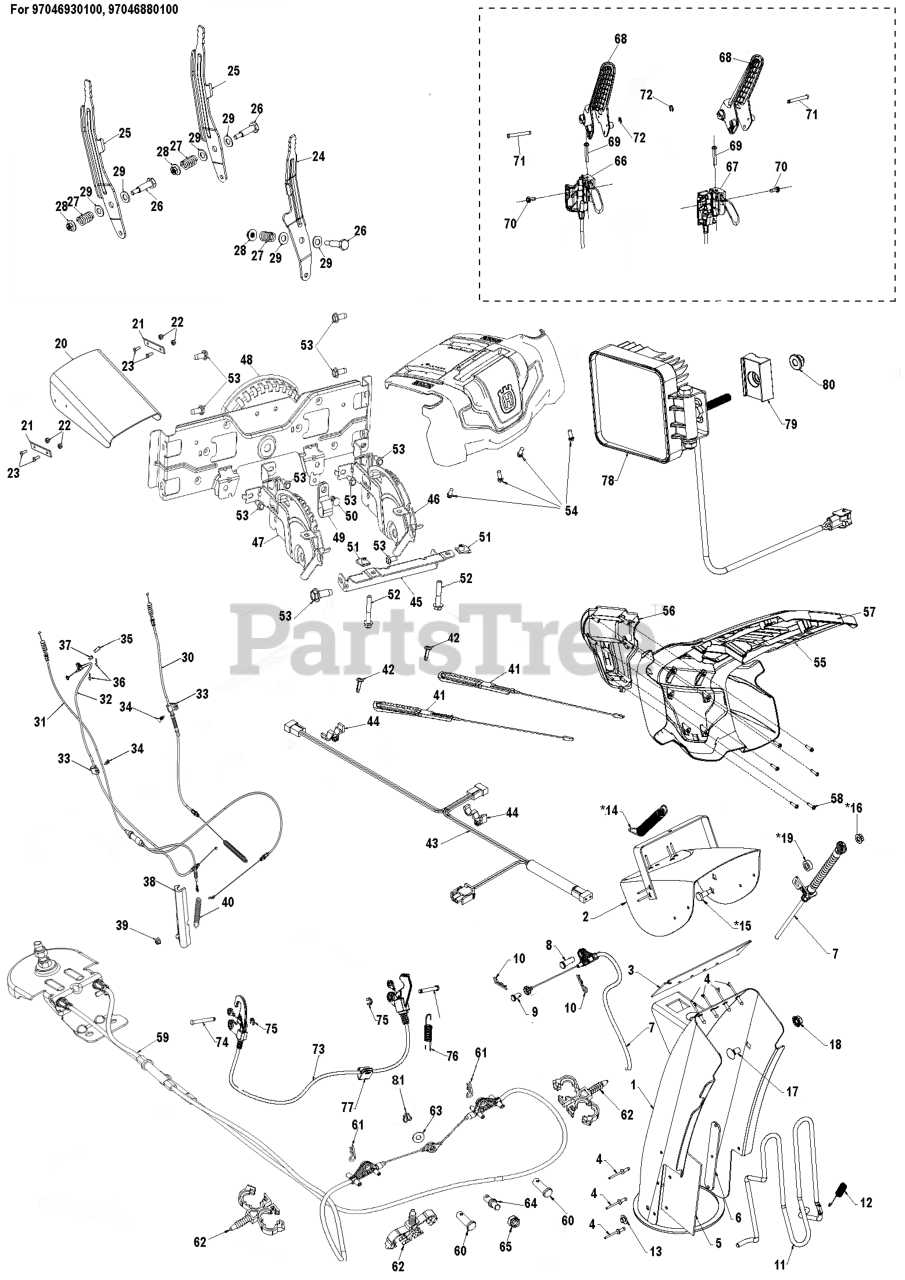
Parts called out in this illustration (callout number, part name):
1	ASM.CHUTE/DEFLECTOR.668
8	PIN CLEVIS 5/16X.875
9	PIN CLEVIS .25 X .31
10	HAIRPIN.SOFT.ZINC.059X1.125
11	GUARD ROD CHUTE GUARD SHORT CL
12	SPRING.CHUTE.GUARD
13	NUT
20	SHIELD.DEFLECTOR.BLACK.SNOW
21	STRAP.DEFLECTOR.SHIELD
22	SCREW.MACHINE.8-32 X 1/2-BLK
23	NUT.HEX.NYLOCK
25	LEVER.CONTROL.SPEED/DEFLEC.BLK
26	BOLT SHOULDER_HEX HD_1/4-20_3/
27	SPRING.COMPRESSION.82LBS
28	NUT HEX_LRG FLG_1_4-20_LOCK
29	WASHER, NYLON FRICTION
31	CABLE IMPELLER
33	CLIP.CABLE.BLK
34	FASTENER.PUSH.O.250X0.783
35	PIN CLEVIS 5/16X.875
36	HAIRPIN.SOFT.ZINC.059X1.125
37	PIN CLEVIS .25 X .31
38	COVER AUGER CABLE
39	NUT HEXAGON FLANGE 5/16-18 ST
40	SPRING EXTENSION; AUGER EXTENS
41	GRIP.HANDLE.HEATED
42	SCREW.PAN.HD.TORX.1/4-20X.750
49	CLIP.CABLE.BLK
50	FASTENER.PUSH.O.250X0.783
51	1/4-20 U NUT
52	SCREW.HEXCAP.1/4X-20X1.500
53	HEX.WASHER.HEAD 1/4-20 X .65
54	SCREW.HWH.13-16-5.8.BZP
55	Consoles
60	PIN CLEVIS 5/16X.875
61	HAIRPIN.SOFT.ZINC.059X1.125
62	CLIP.CONDUIT.DOUBLE LOOP
63	WASHER FLAT_.250 X .625 X .06
64	Pins
64	Clevis Pins
65	NUT HEXAGON 1/4-20 ST ZPB
66	CABLE.POWER STEERING.LHS
67	CABLE.POWER STEERING.RHS
68	LEVER ENGAGMENT
69	SCREW HEX_WASH_13-16 X 1.50_H
70	SCREW 14-20 X 5/8
71	PIN.GROOVED
73	CABLE INTERLOCK CONTROL ACETAL
74	PIN.GROOVED
76	SPRING RETURN_INTERLOCK_DSST
77	CLIP.CABLE.BLK
78	LED LIGHTS
79	MOUNTING BRACKET LIGHT MOUNTIN
